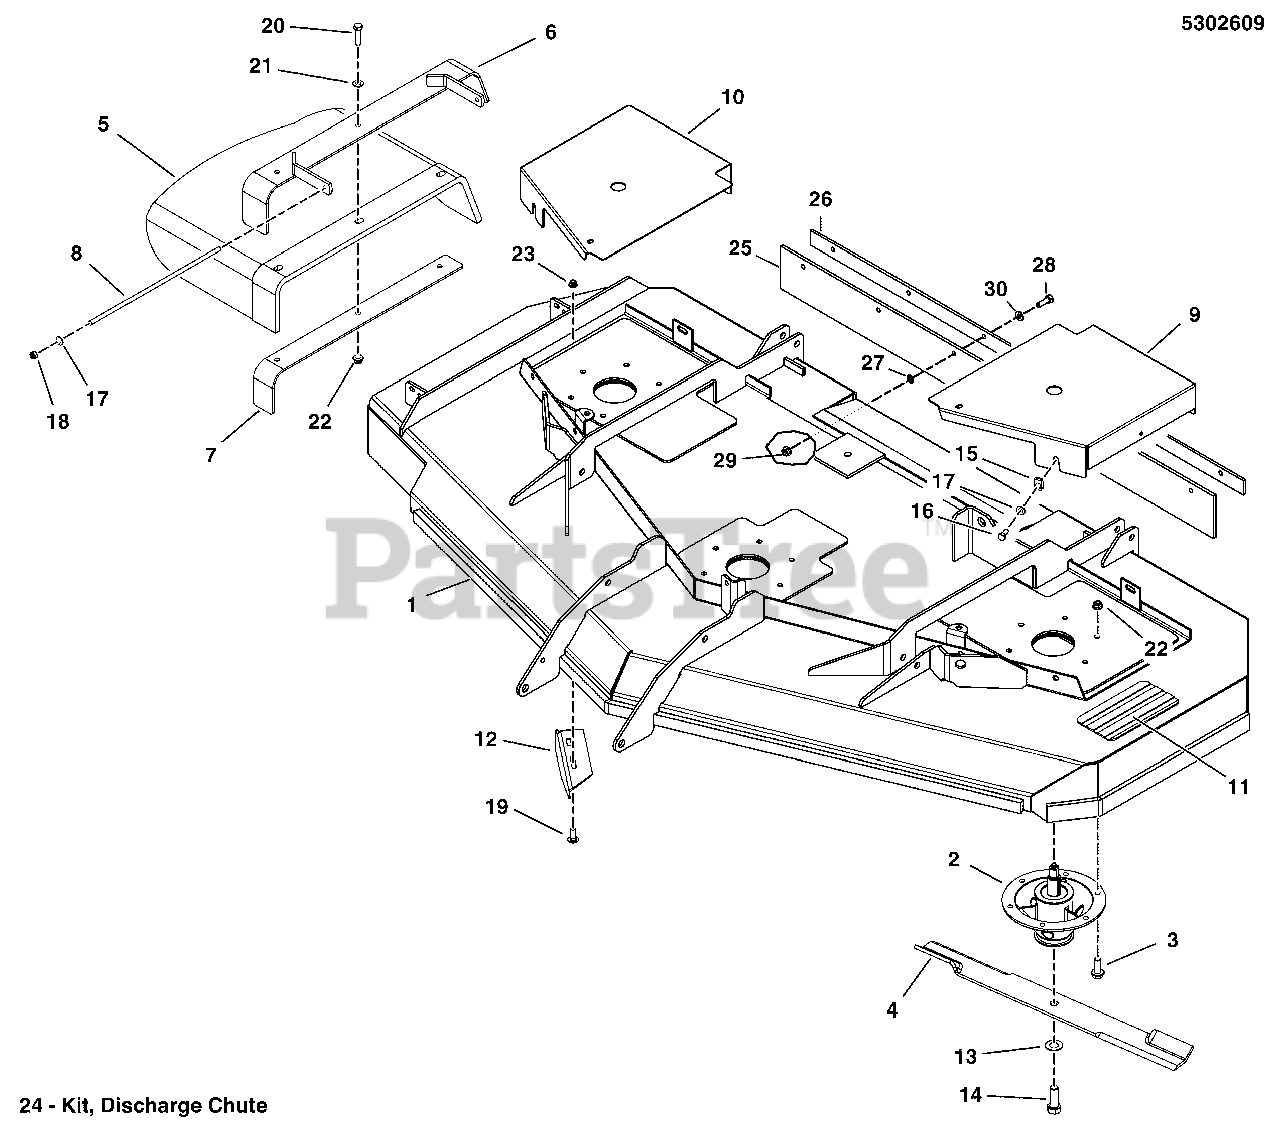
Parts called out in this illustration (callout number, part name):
1	DECK SHELL W/ DECALS, 72, S200XT
1	DECK SHELL W/DECALS, 72, 200XT-DOM
2	SPINDLE ASSM, CAST IRON 8.0-6 BOLT
2	ASSM, SPINDLE, LARGE CAST
3	BOLT, 3/8-16 X 1-1/4, FLANGE, GD 5, CZ
4	BLADE, 25 X 25 X 2.50, HIGH LIFT (SET OF 3)
4	BLADE, 25 X 25 X 2.50, HIGH LIFT
5	CHUTE, DISCHARGE, BEND RUBBER (SV)
6	WELD, FRAME, CHUTE, 72 - BLK
7	SUPPORT, DICHARGE CHUTE, 61/72 - BLK
8	ROD, MOUNT, CHUTE, 72, CZ
9	GUARD, DECK, LH, S200XT-72 - RED
10	GUARD, DECK, RH, S200XT-72 - RED
11	SAFETY WALK, 4.00 X 7.50
12	PLATE, DEFLECTOR, 72 - BLK
13	WASHER, 5/8 GRADE 8, YZ
14	BOLT, 5/8-11 X 1-3/4 GD8
15	BODY CLIP, 5/16-18-7GA MATERIAL
16	BOLT, 5/16-18 X 3/4 GD5
17	WASHER, 5/16" SAE
18	NUT, 5/16-24 HEX NYLON LOCK
19	BOLT, 5/16-18 X 3/4, CARRIAGE
20	BOLT, 3/8-16 X 1-1/2 GD5 YZ
21	WASHER, 3/8 SAE
22	NUT, 3/8-16 HEX NYLOCK FLANGE
23	NUT, 5/16-18 HEX NYLOCK FLANGE
24	KIT, DISCHARGE CHUTE, 72, S200XT
25	FLAP, STRIPER, 72 DECK
26	PLATE, SUPPORT, 72 - BLK
27	5/16 PUSH-ON NUT RETAINER, STL, CZ
28	BOLT, 5/16-18 X 1 GD5 YZ
29	NUT, 5/16-18 HEX NYLOCK FLANGE
30	WASHER, 5/16" SAE
